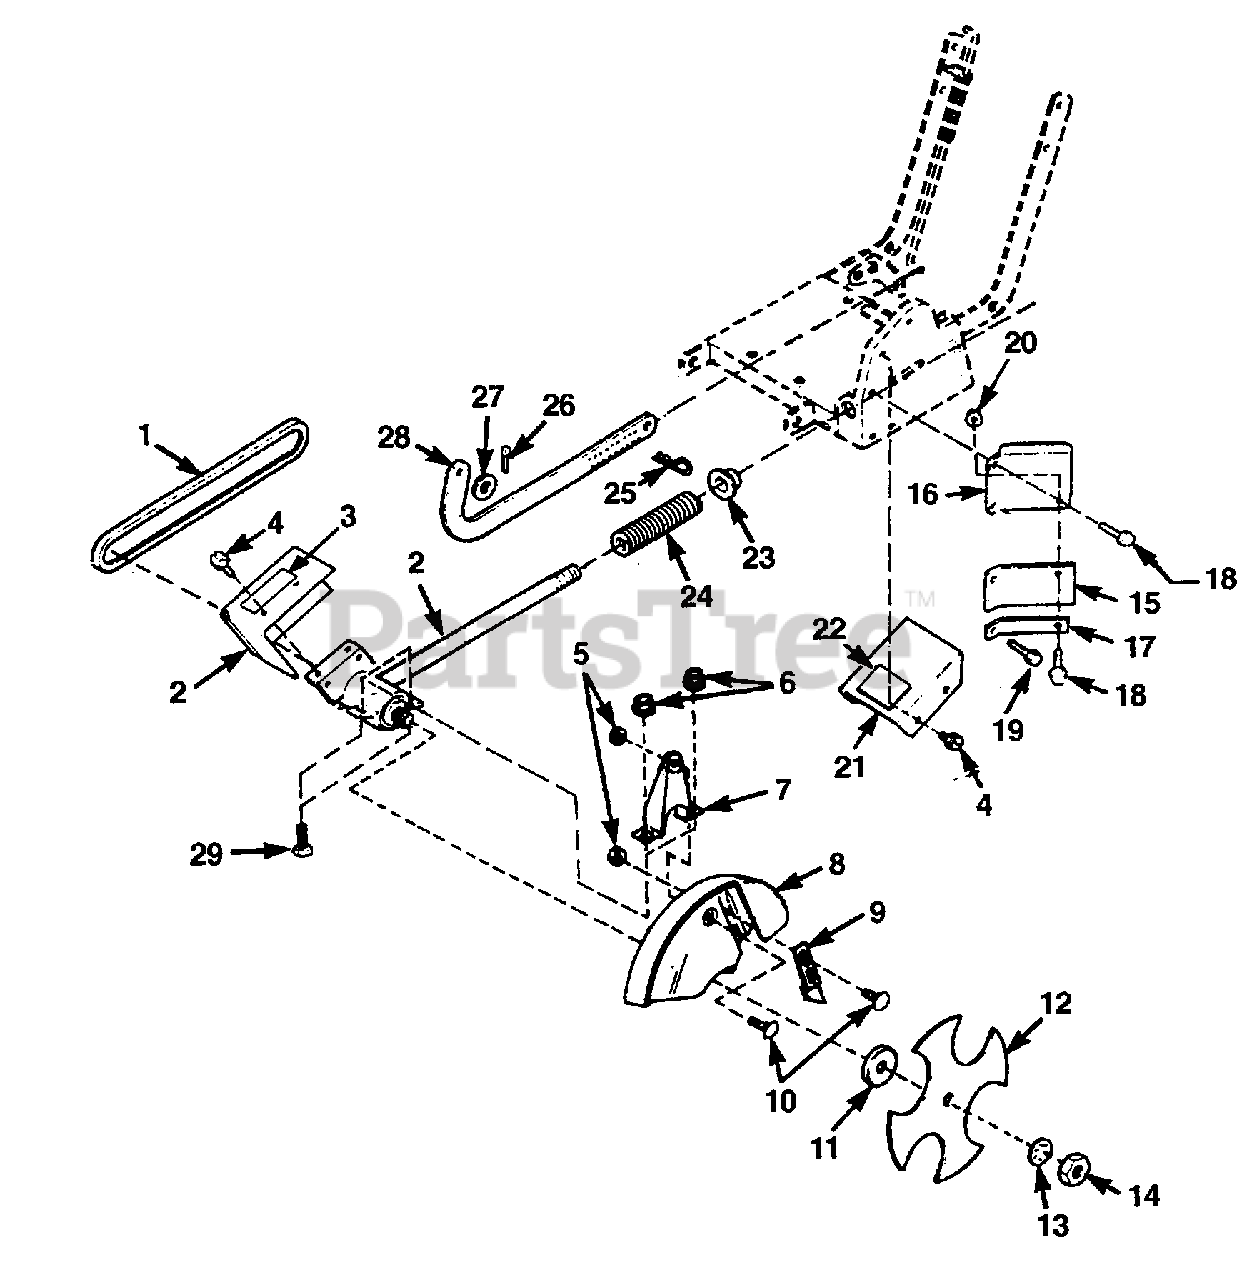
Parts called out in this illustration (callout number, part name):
2	HEAD-Cutter w/Cutter Guard
3	DECAL-Warning
4	SCREW-(1/4-20 X 1/2")
5	NUT-(1/4-20)
6	NUT-Hex w/Washer
7	BRACKET-Guard Support
8	GUARD-Blade
9	FINGER-Guide
10	BOLT-Carriage (1/4-20 x 5/8")
11	WASHER-Dust Shield
12	BLADE-Star
13	WASHER-Lock (5/8")
14	NUT-Jam (5/8"-18)
15	DEBRIS FLAP ASSEMBLY, FLAP-Debris (Rubber)
16	DEBRIS FLAP ASSEMBLY, SHIELD-Debris
17	DEBRIS FLAP ASSEMBLY, BRACKET-Debris
18	DEBRIS FLAP ASSEMBLY, SCREW-Hex Hd. (1/4-20 X 5/8")
19	DEBRIS FLAP ASSEMBLY, SCREW-Hex Hd. (1/4-20 X 3/4")
20	DEBRIS FLAP ASSEMBLY, NUT-(1/4-20)
21	GUARD-Engine Pulley
22	DECAL-Safety
23	BUSHING-Nylon
24	SPRING-Cutter Head
25	PIN-Cotter Hair
26	PIN-Cotter
27	WASHER-Flat
28	RATCHET-Depth Control
